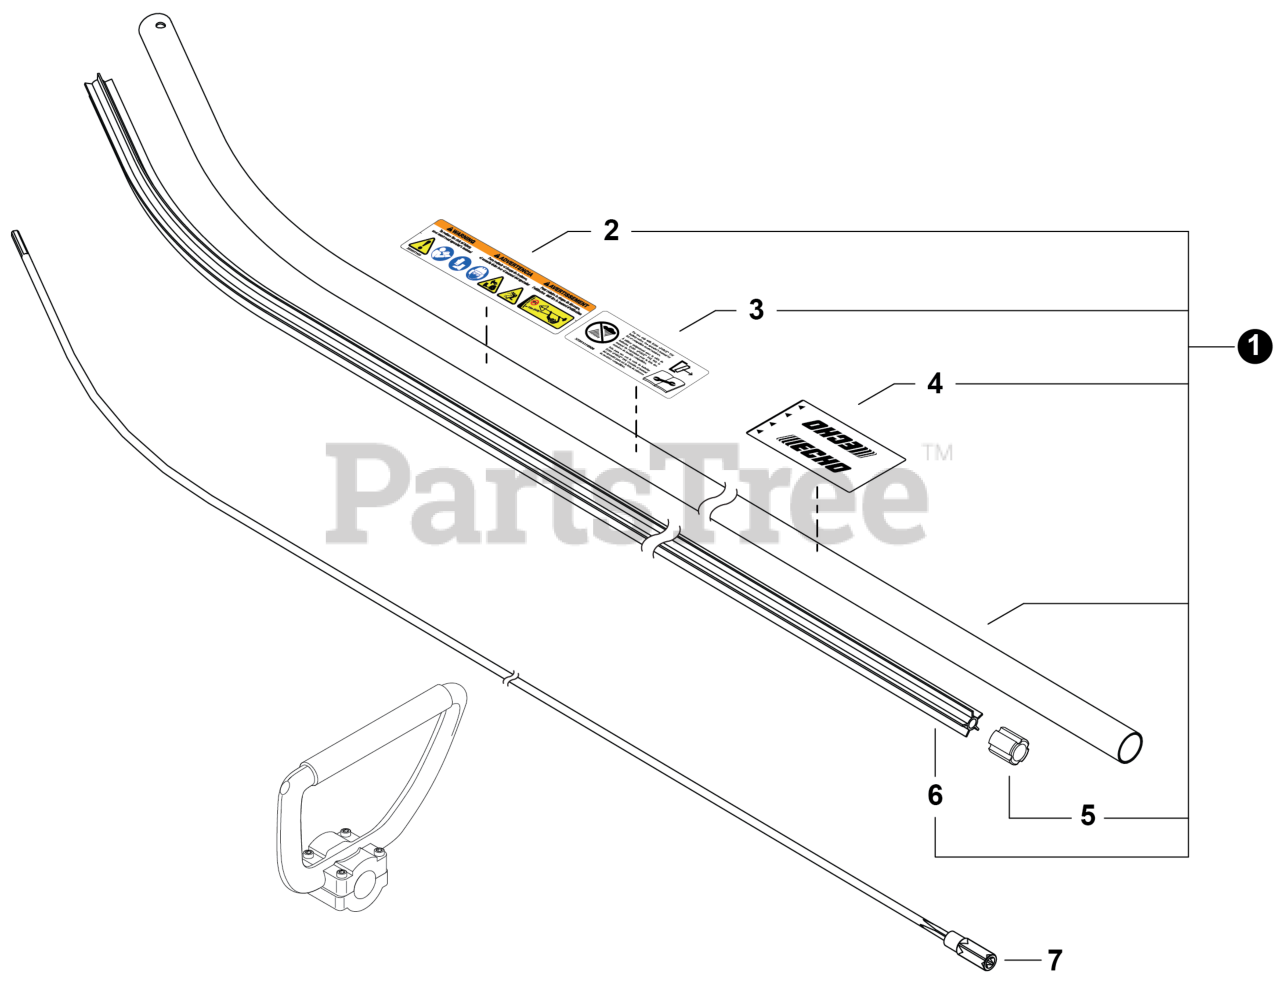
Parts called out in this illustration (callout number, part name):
1	MAIN PIPE ASSY
2	LABEL - CAUTION ISO
3	LABEL - CAUTION - UL
4	LABEL - HANDLE LOCATION
6	LINER, FLEXIBLE
7	DRIVESHAFT - FLEXIBLE
